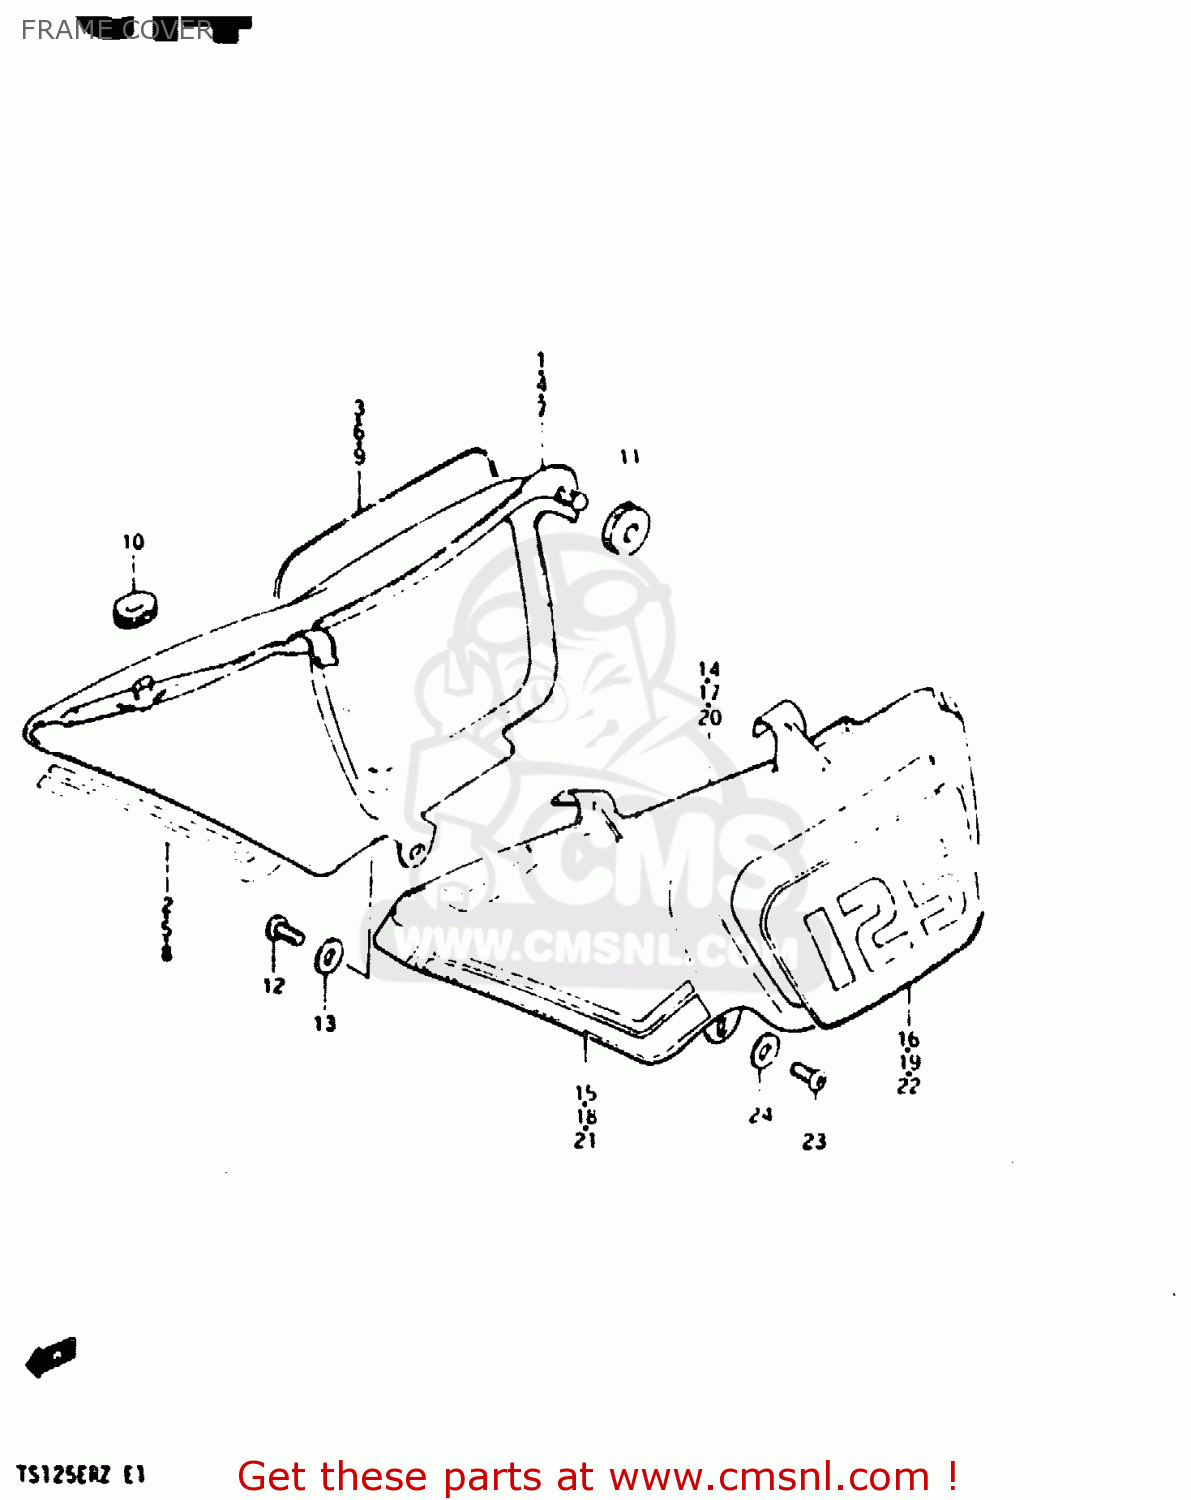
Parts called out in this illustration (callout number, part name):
1	COVER, FRAME RH (YELLOW)
2	TAPE SET, FRAME COVER RH
3	EMBLEM,FRAME COVER,R
4	COVER, FRAME RH (RED)
5	TAPE SET, FRAME COVER RH
6	EMBLEM,FRAME COVER,R
7	COVER, FRAME RH (BLACK)
8	TAPE SET, FRAME COVER RH
9	EMBLEM, FRAME COVER RH
10	CUSHION
11	CUSHION
12	SCREW
13	WASHER
14	COVER,FRAME,L(YELLOW)
15	TAPE SET, FRAME COVER LH
16	EMBLEM, FRAME COVER LH
17	COVER, FRAME LH (RED)
18	TAPE SET,FRAME COVER,L
19	EMBLEM, FRAME COVER LH
20	COVER, FRAME LH (BLACK)
21	TAPE SET,FRAME COVER,L
22	EMBLEM, FRAME COVER LH
23	SCREW
24	WASHER
